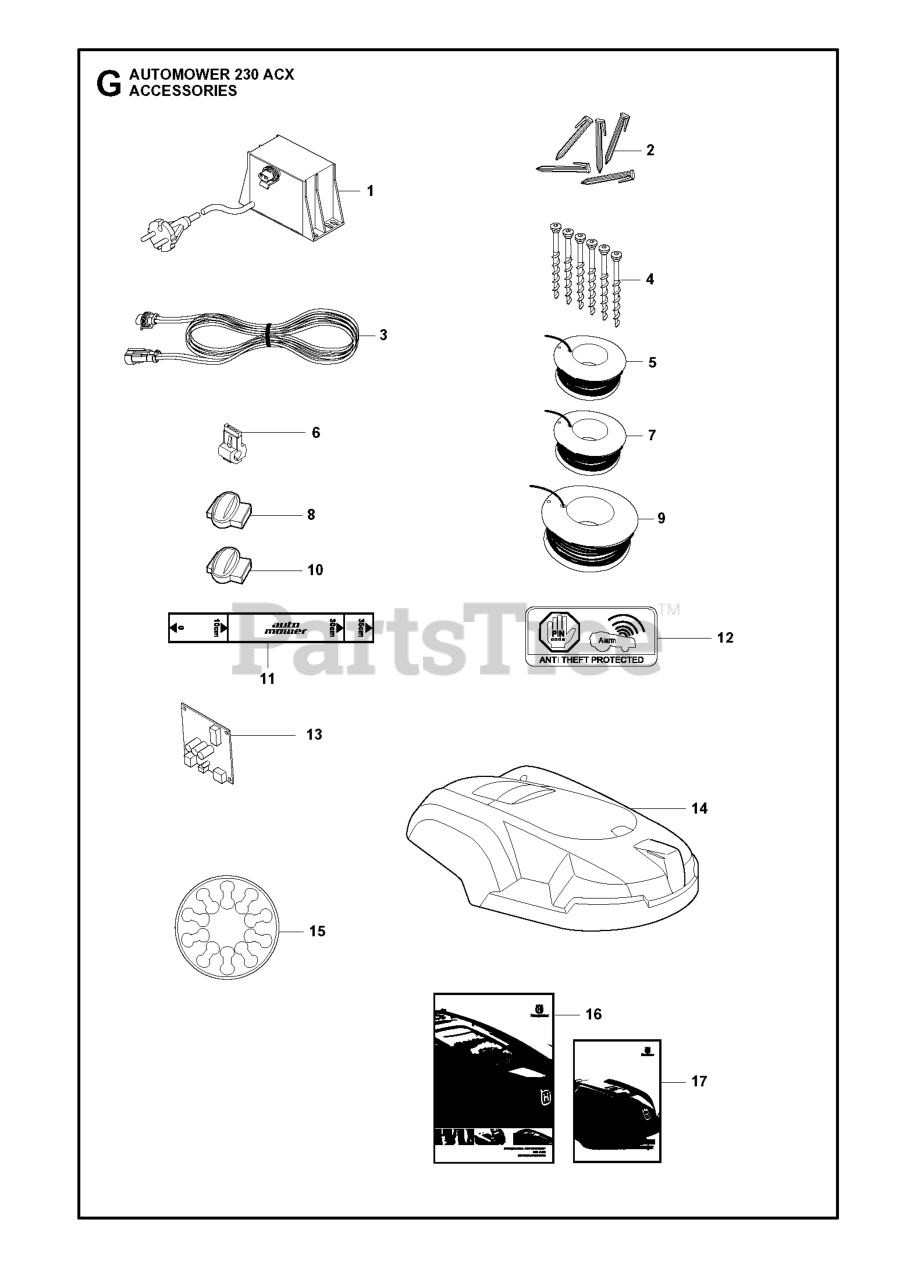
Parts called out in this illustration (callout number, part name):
1	TRANSFORMER US
2	STAPLES (100 CT BAG)
2	STAPLE 100 PCS, BLISTER
3	LOW VOLT WIRING
4	SCREW KIT CS
4	SCREW 3 PCS, BLISTER PACK
5	LOOP WIRE 150M
5	WIRE 150M, BLISTER
6	CONNECTOR 5 PCS, BLISTER
6	BRAKER
7	LOOP WIRE 250M
8	SPLICE KIT
8	COUPLER SPLICER, 5 PCS,
9	WIRE 500M
10	SPLICE CONNECTOR 50 PCS/PK
11	RULER / CENTIMETERS
12	DECAL
13	CIRCUIT BOARD ASSY PCBA GEN BO
14	BODY WATER, DARK BLUE
14	BODY FIRE, ORANGE
14	BODY EARTH, BROWN
14	BODY AIR, CREAM WHITE
